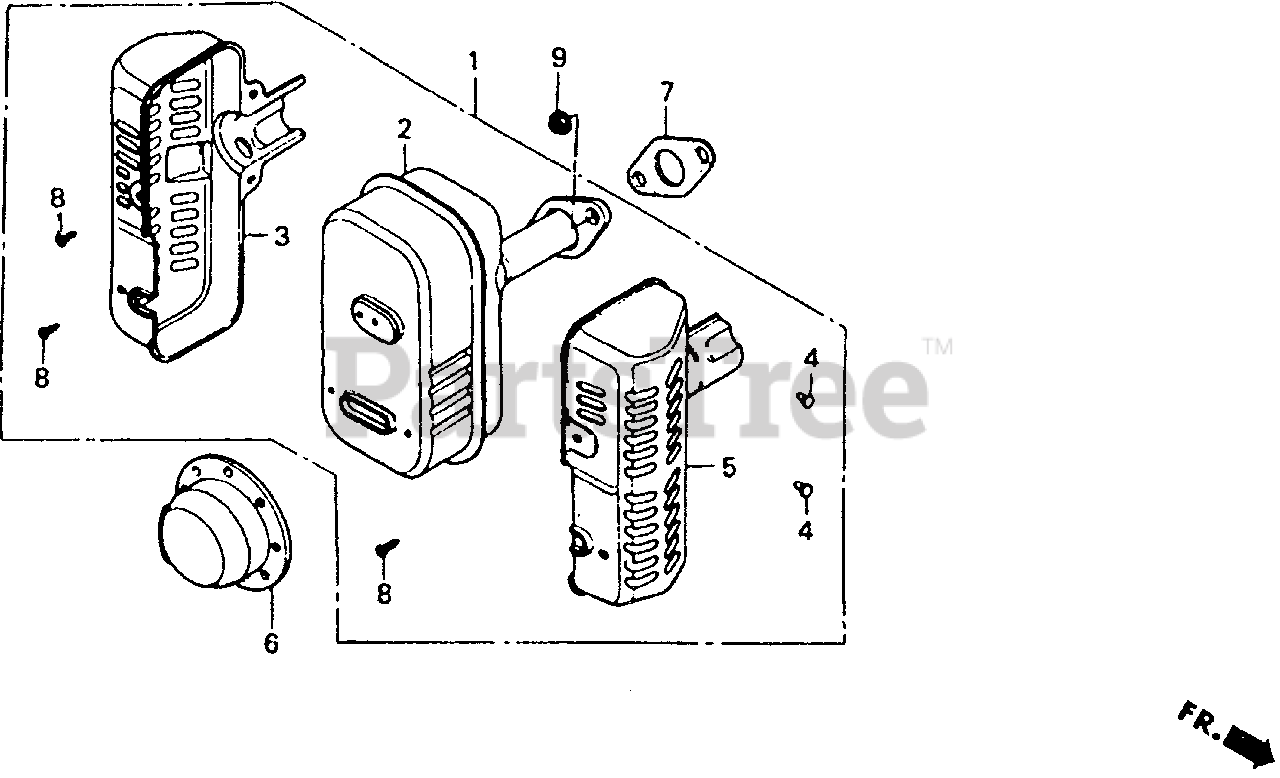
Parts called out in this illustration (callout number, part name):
2	MUFFLER
3	PROTECTOR, L. MUFFLER
4	RIVET (4X5)
5	PROTECTOR, R. MUFFLER
6	CAP, MUFFLER
7	GASKET, MUFFLER
8	SCREW, TAPPING (4X8)
9	NUT, FLANGE (8MM)
